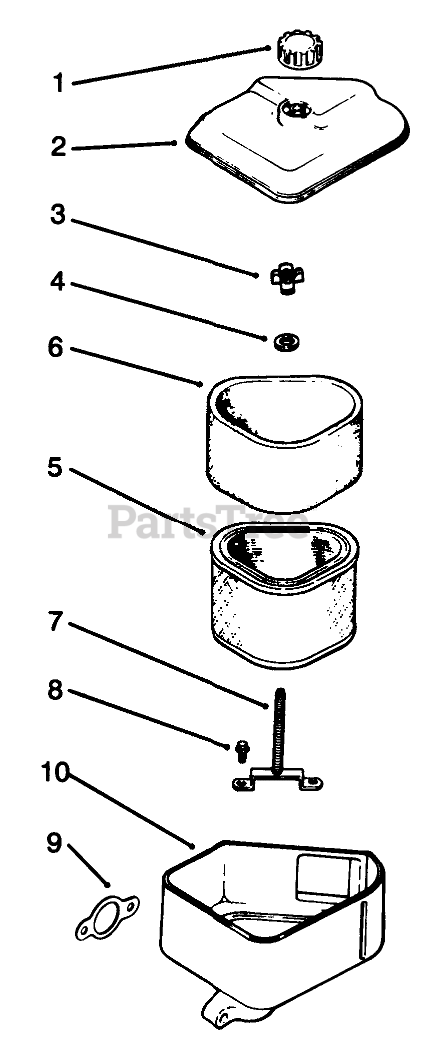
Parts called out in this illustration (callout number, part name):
1	Knob-Air Cleaner Cover (Only On: 72042, 72043, 72062, 72063)
2	Cover-Air Cleaner (Only On: 72042, 72043, 72062, 72063)
3	Nut-Wing (Only On: 72042, 72043, 72062, 72063)
4	Washer-Flat (Only On: 72042, 72043, 72062, 72063)
5	Element-Air Cleaner (Only On: 72042, 72043, 72062, 72063)
6	Precleaner-Element (Only On: 72042, 72043, 72062, 72063)
7	Stud-Mounting Plate (Only On: 72042, 72043, 72062, 72063)
8	Screw-Mounting Plate (Only On: 72042, 72043, 72062, 72063)
9	Gasket-Air Cleaner (Only On: 72042, 72043, 72062, 72063)
10	Base-Air Cleaner (Only On: 72042, 72043, 72062, 72063)
